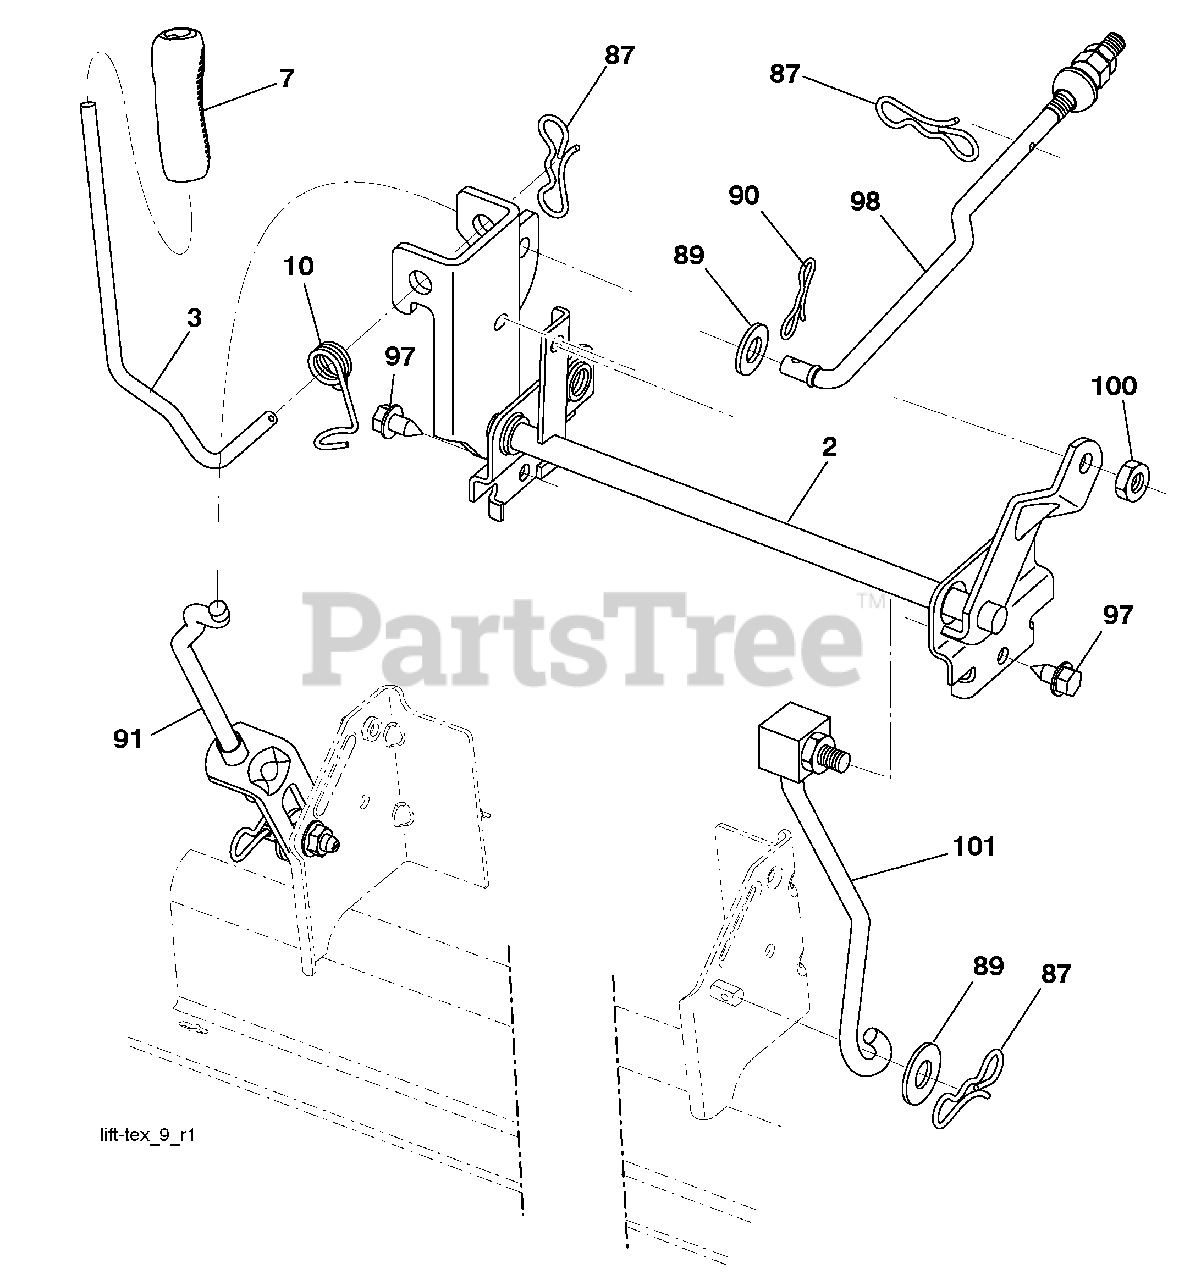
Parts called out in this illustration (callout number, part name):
2	Shaft Asm., Lift
3	Lever Asm., Lift RH
7	Grip, Lever
10	Spring Torsion
87	Pin Cotter 7/16 Bow Tie Lock
89	Washer Clear Zinc
90	Pin Cotter 5/16 Bow Tie Lock
91	Link Asm Lift LH Rear
97	Screw Hex Wsh. THDR 3/8-16 x 3/4
98	Link Lift Susp. Front Mower
100	Nut Centerlock 3/8-16 unc
101	Link Asm. Lift FXD
